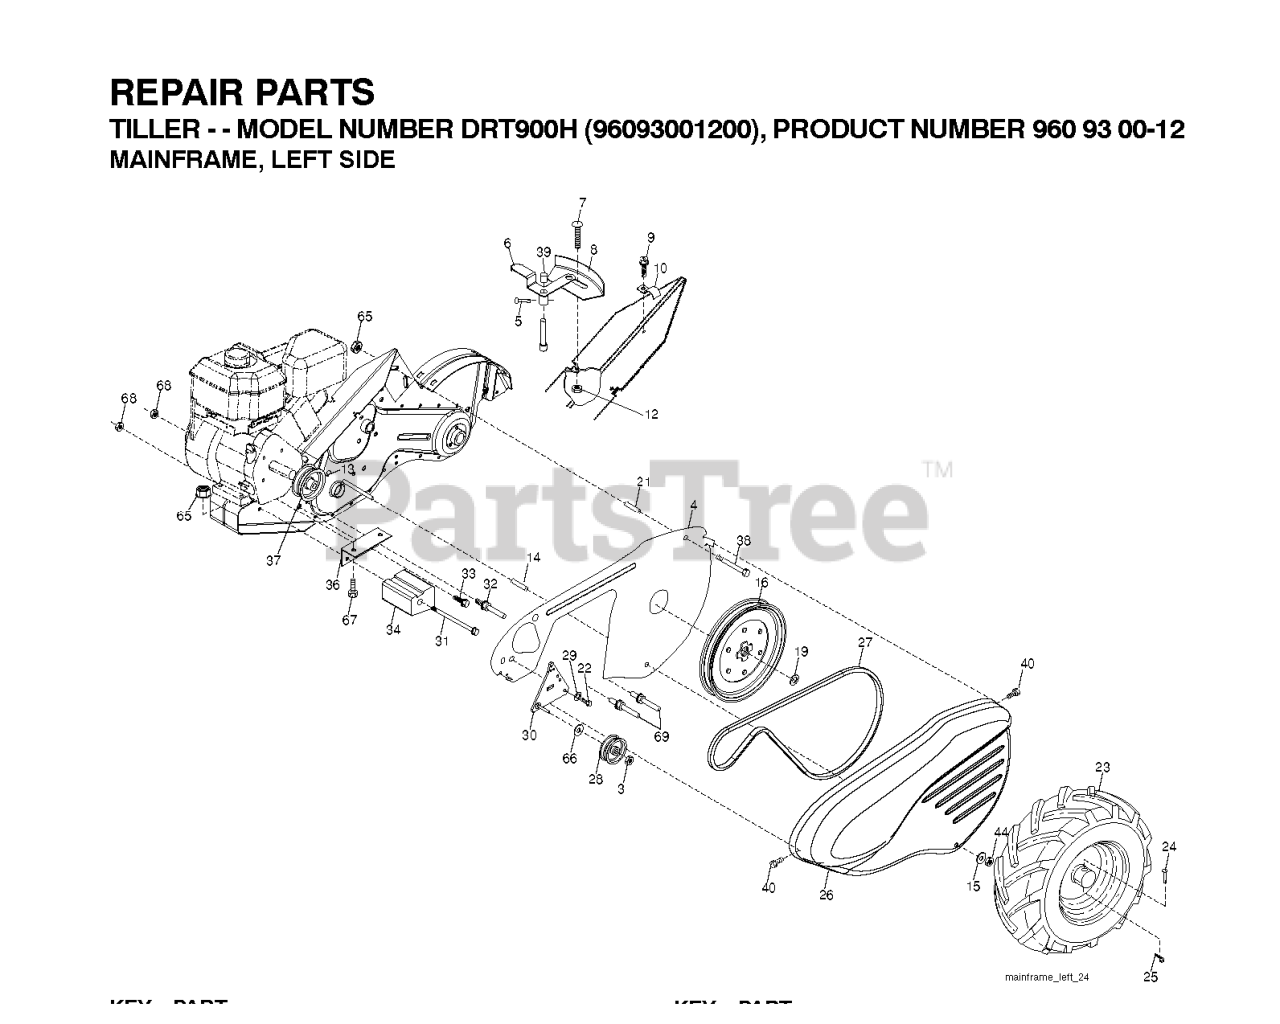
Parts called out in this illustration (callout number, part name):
3	LOCKNUT
4	SHIELD.INNER.BELT.GUARD.RT
5	PIN.SPIROL.FLARED
6	LEVER.ASM.SHIFT.RED
8	RP.PANEL.SHIFT
9	TAPPING SCREW
10	CONDUIT.CLIP.PLATED
12	NUT
14	SPACER CRT
15	WASHER
16	SHEAVE, TRANSMISSION
19	RETAINING RING LT
21	SPACER-SPLIT.327 X .42
23	TIRE.13X5-6.CHEVRON.TILLER
24	RIVET,DRILLED
25	RETAINER M
26	RP BELT GUARD
27	V-BELT
28	PULLEY-IDLER TI
30	BRACKET.ASM.IDLER.BLACK
31	BOLT.FIN.HEX.3/8-16UNC
32	SHIFT ARM CRT
33	BOLT
34	COUNTERWEIGHT.LH.CRT
36	BRACKET LH CRT
37	RP.ENGINE PULLEY
38	BOLT
39	CAP.PLUNGER.BLACK
40	SCREW.HEX.WSH.SLT.#10-24X.50
44	NUT.71038.31-18.HEX.NYLOCK
65	LOCKNUT-FLANGE 5/16-18
66	WASHER
67	BOLT
69	KEEPER.BELT.ENGINE
